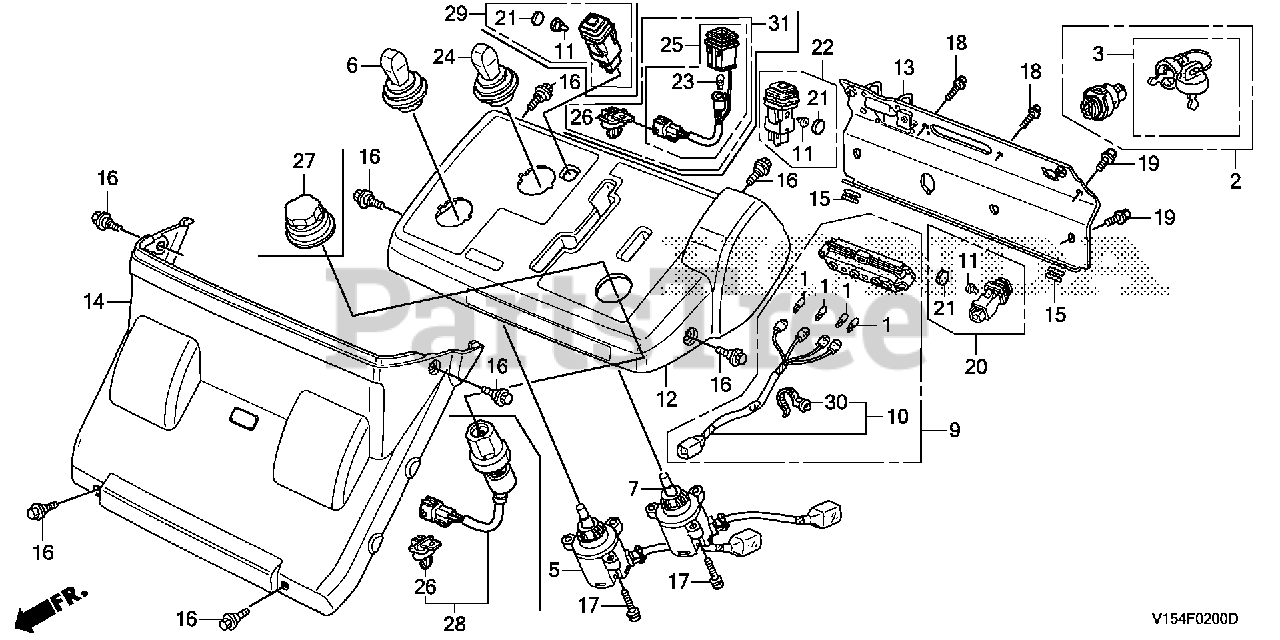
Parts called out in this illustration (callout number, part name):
1	BULB, WEDGE BASE (24V 1.4W)
2	SWITCH ASSY., COMBINATION
3	KEY ASSY., COMBINATION SWITCH
5	SWITCH ASSY., CHUTE CONTROL
6	BOOT, RUBBER (BLACK)
7	SWITCH ASSY., CHUTE CONTROL
9	INDICATOR ASSY., WARNING
11	SOCKET ASSY., LAMP
12	PANEL, CONTROL *NH296* (ALPS GRAY)
13	PANEL, RR.
14	COVER, FR. PANEL *NH296* (ALPS GRAY)
16	BOLT, CONTROL PANEL
17	BOLT-WASHER (5X20)
18	SCREW-WASHER (4X16)
19	BOLT, FLANGE (6X12)
21	CAP, VALVE
23	BULB (28V/2.5W)
24	BOOT, RUBBER (LIGHT GRAY)
26	CLIP, CONNECTOR (DARK GREEN)
27	KNOB, MODE SELECT
28	SWITCH ASSY., MODE SELECT
29	SWITCH ASSY., CLUTCH ON OPERATING
30	BAND, WIRE HARNESS (110MM) (BROWN)
31	SWITCH ASSY., CLUTCH ON OPERATING
